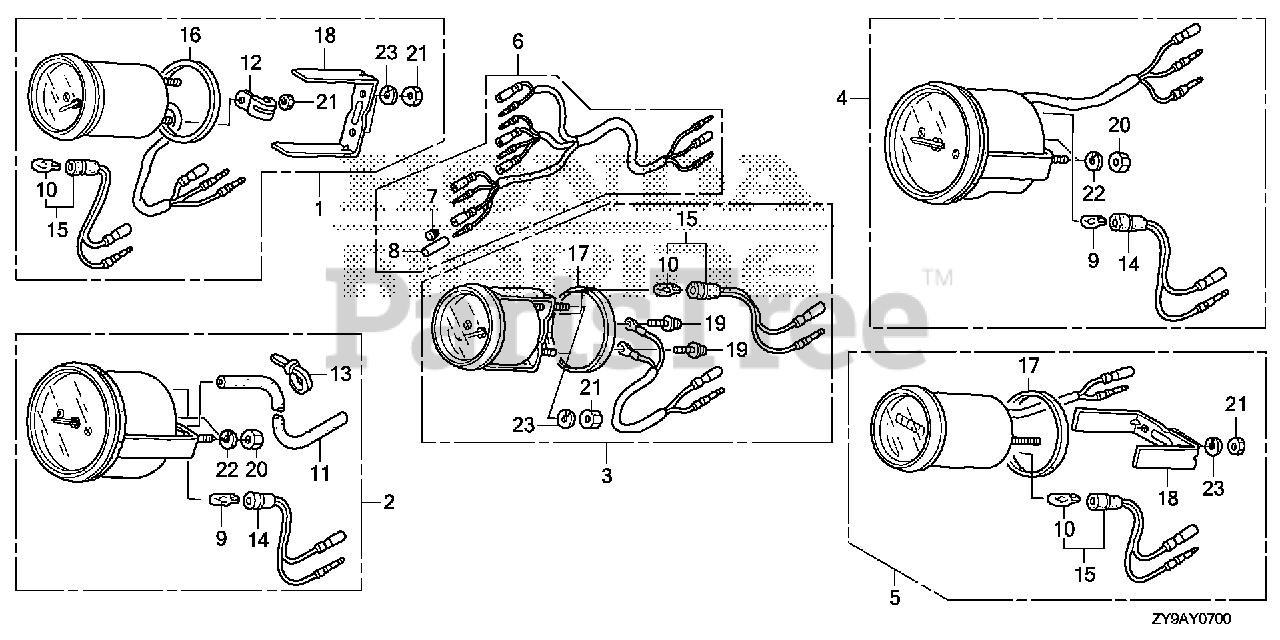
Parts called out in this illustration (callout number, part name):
1	METER KIT, TRIM (WHITE)
1	METER KIT, TRIM (B) (BLACK)
2	SPEEDOMETER KIT (WHITE)
2	SPEEDOMETER KIT *NHA85* (B) (BLACK)
3	METER KIT, VOLT (WHITE)
3	METER KIT, VOLT *NHA85* (B) (BLACK)
4	METER KIT, TACHO
4	METER KIT, TACHO (B)
5	METER KIT, HOUR (WHITE) (NA USE ALT:39700-ZW5-000ZA)
5	METER KIT, HOUR (B) (NA USE ALT:39700-ZW5-000ZA)
6	HARNESS ASSY., METER (B)
7	PLUG, CONNECTOR (INNER) (TROLLING CONTROL)
8	PLUG, CONNECTOR (OUTER) (ENGINE NO.)
9	BULB, WEDGE BASE (T10) (12V 1.7W) (STANLEY)
10	BULB, WEDGE BASE (12V1.7W) (TOSHIBA)
11	TUBE, SPEED METER (4X7X8000)
12	CLAMP
13	BAND, SELF-LOCK
14	SOCKET
15	SOCKET
16	GASKET (TO 1015209) (FROM 1015210)
17	GASKET
18	BRACKET (TO 1015209) (FROM 1015210)
19	SCREW-WASHER (3X22)
20	NUT, HEX. (5MM)
21	NUT, HEX. (4MM)
22	WASHER, SPRING (5MM)
23	WASHER, SPRING (4MM)
